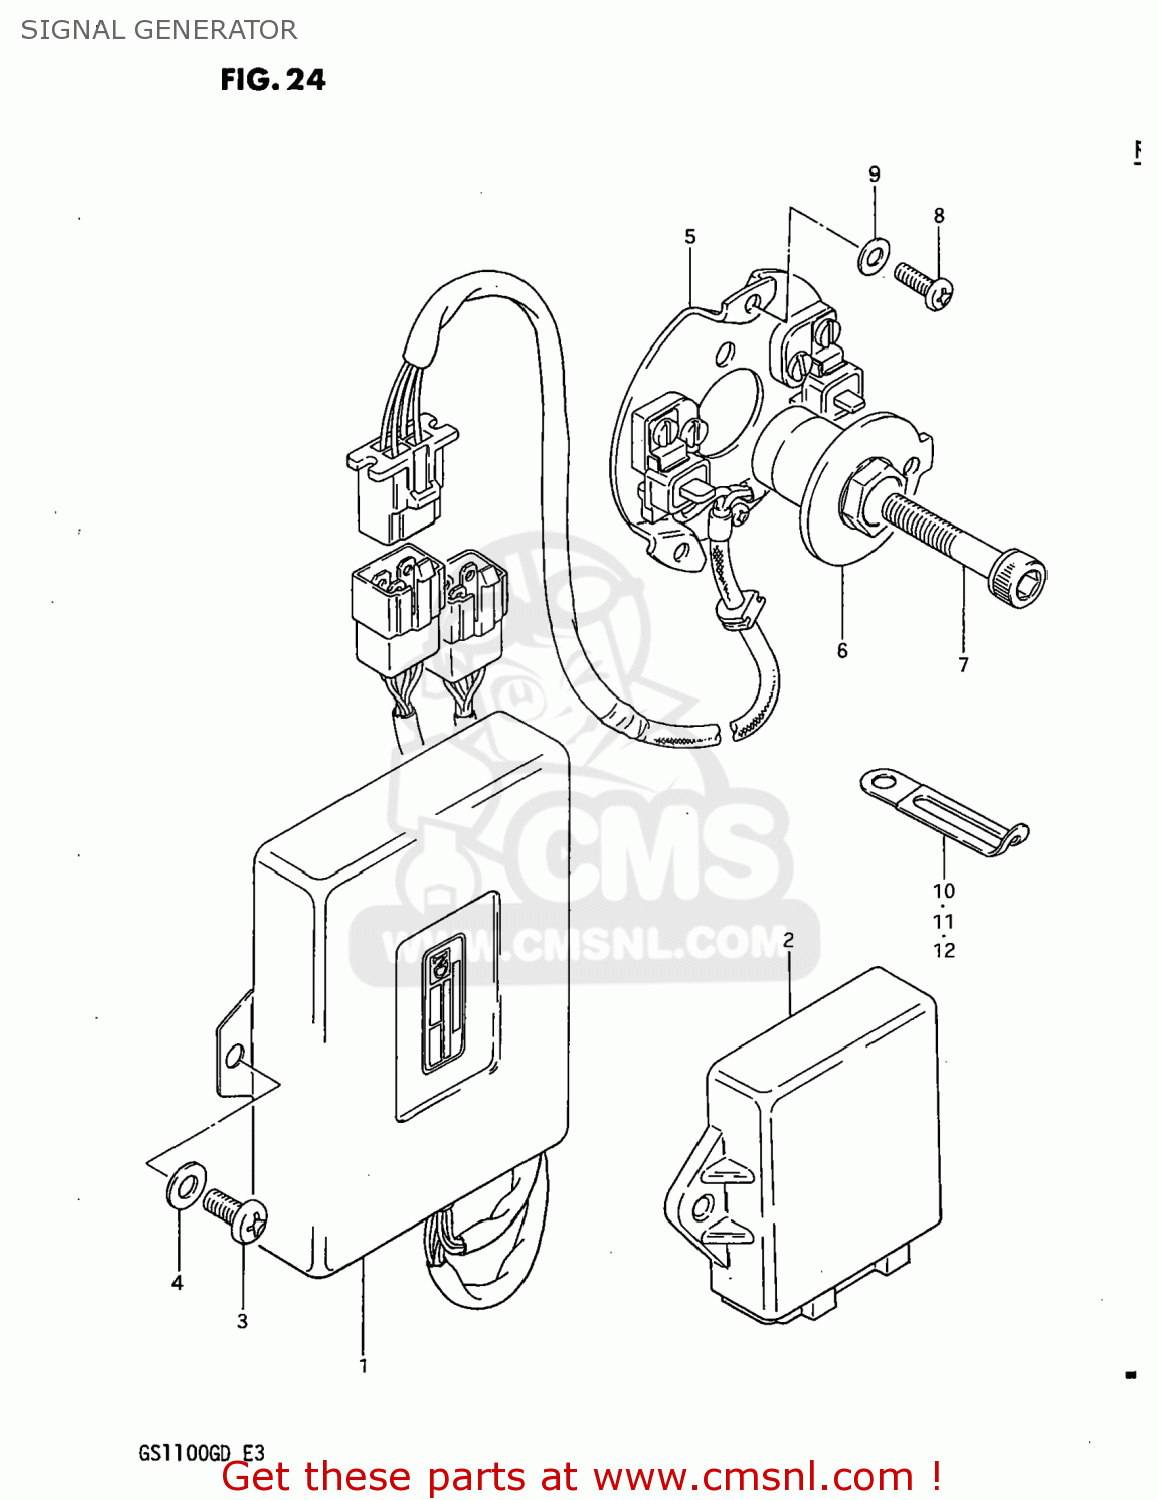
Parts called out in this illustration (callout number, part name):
1	IGNITER UNIT ASSEMBLY
2	IGNITOR UNIT,ESA
3	SCREW 6X12
4	WASHER
5	STATOR,SIGNAL GENERATOR
6	ROTOR,SIGNAL
7	BOLT
8	SCREW(5X12)
9	WASHER
10	CLAMP L:35
11	CLAMP
12	CLAMP
